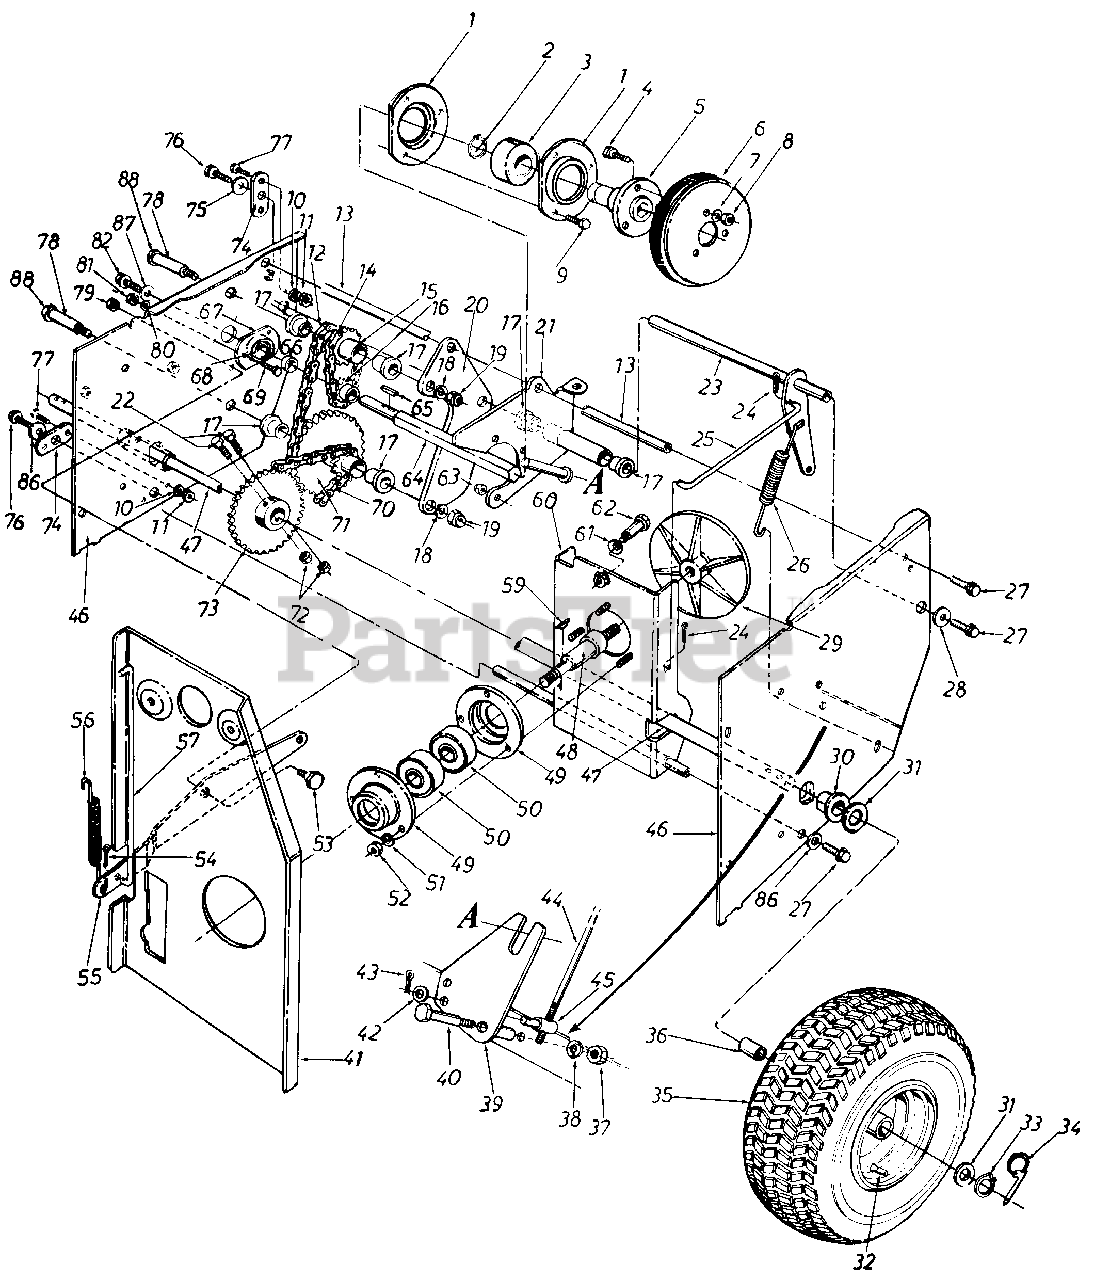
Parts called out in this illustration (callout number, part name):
1	Bearing Housing
2	Snap Ring-1.0" Dia.
3	Ball Brg. .25MM x 52MM x 15MM Thk.
4	Hex Sems Bolt 5/16-18 x .75" Lg.
5	Friction Wheel Adapter
6	Friction Wheel Ass'y.
7	L-Wash. 5/16" I.D.
8	Hex Nut 5/16-18 Thd.
9	Hex Bolt 1/4-28 x .62" Lg.
10	L-Wash 1/4" I.D.
11	Llex Nut 1/4-20 Thd.
12	#41 Chain-1/2" Pitch x 43 Links
13	Sliding Support Axle
14	#41 Chain-1/2" Pitch x 19 Links
15	9 and 14 Teeth Sprocket Hub Ass'y.
16	8 Teeth Sprocket
17	Flange Bearing .63" I.D.
18	L-Wash. 3/8" I.D.-H.D.
19	Hex L-Jam Nut 3/8-24 Thd.
22	Hex Bolt 5/16-24 x 1.75" Lg.
23	Drive Clutch Brkt. Ass'y.
24	Inter. Cot. Pin 5/16" Dia.
25	Drive Clutch Rod .31" Dia. x 7.38" Lg.
26	Extension Spring 4.31" Lg.
27	Hex L-Bolt 5/16-18 x .62"
28	Fl-Wash. .345" I.D. x .75" O.D.
29	Aluminum Drive Plate
30	Flange Brg. w/Flats
31	Thrust Washer 1.03" I.D.
32	Tubeless Air Valve
33	Snap Ring 1.0" Shaft
35	Wheel Ass'y. Comp. 16 x 4.8
36	Bearing 1.0" I.D.
37	Hex Jam Nut 3/8-16 Thd.
38	L-Wash. 3/8" I.D.
41	Engine Brkt. Ass'y.
42	Fl-Wash. .344" I.D. x .62" O.D.
43	Cotter Pin 3/32" Dia. x .75" Lg.
44	Shifting Rod
45	Adjustment Ferrule
46	Frame Ass'y.
47	Free Wheeling Axle
48	Drive Plate Spindle
49	Bearing Housing
50	Ball Brg. .787" I.D. x 1.85" O.D.
51	L-Wash. 5/16" I.D.t
52	Hex Nut 5/16-18 Thd.
53	Shld. Bolt .625" Dia. x .170" Lg.
54	Inter. Cotter Pin 5/16" Dia.t
55	Auger Clutch Brkt.
56	Extension Spring .38" O.D. x 3.18" Lg.
57	Auger Clutch Rod .31" Dia. x 10.62" Lg.
59	#61 Hi-Pro Key 3/16" x 5/8" Dia.
62	Shld. Bolt
63	Hex Ins. Jam Nut 1/4-28 Thd.
65	#9 Hi-Pro Key 3132" x 518" Dia.
66	Spacer .51" l.D. x .69" o.r
67	Bearing Housing
68	Ball Bearing
69	Hex Bolt 1/4-20 x .62" Lg.t
70	#420 Chain .50" Pitch x 37 Link
71	9 and 32 Teeth Sprocket Hub Ass'y.
72	Hex L-Nut 5/16-24 Thd.
73	28 Teeth Sprocket Hub Ass'y.
74	Pivot Axle Brkt.
75	Fl-Wash. .345" I.D. x .75"
76	Hex L-Bolt 5/16-18 x .62"
77	Hex Bolt 1/4-20 x .62" Lg.
78	Sprocket Hub Tubing 1.88"
79	Hex Cent. L-Nut 3/8-16 Thd.
80	L-Wash. 1/4'1 I.D
81	Hex Nut 1/4-20 Thd.t
82	Hex L-Bolt 5/16-18 x .62"
86	Fl-Wash. .344" I.D. x .875"
87	Bell-Wash. .345" I.D. x .88"
88	Hex Bolt 3/8-24 x 2.75" Lg.
